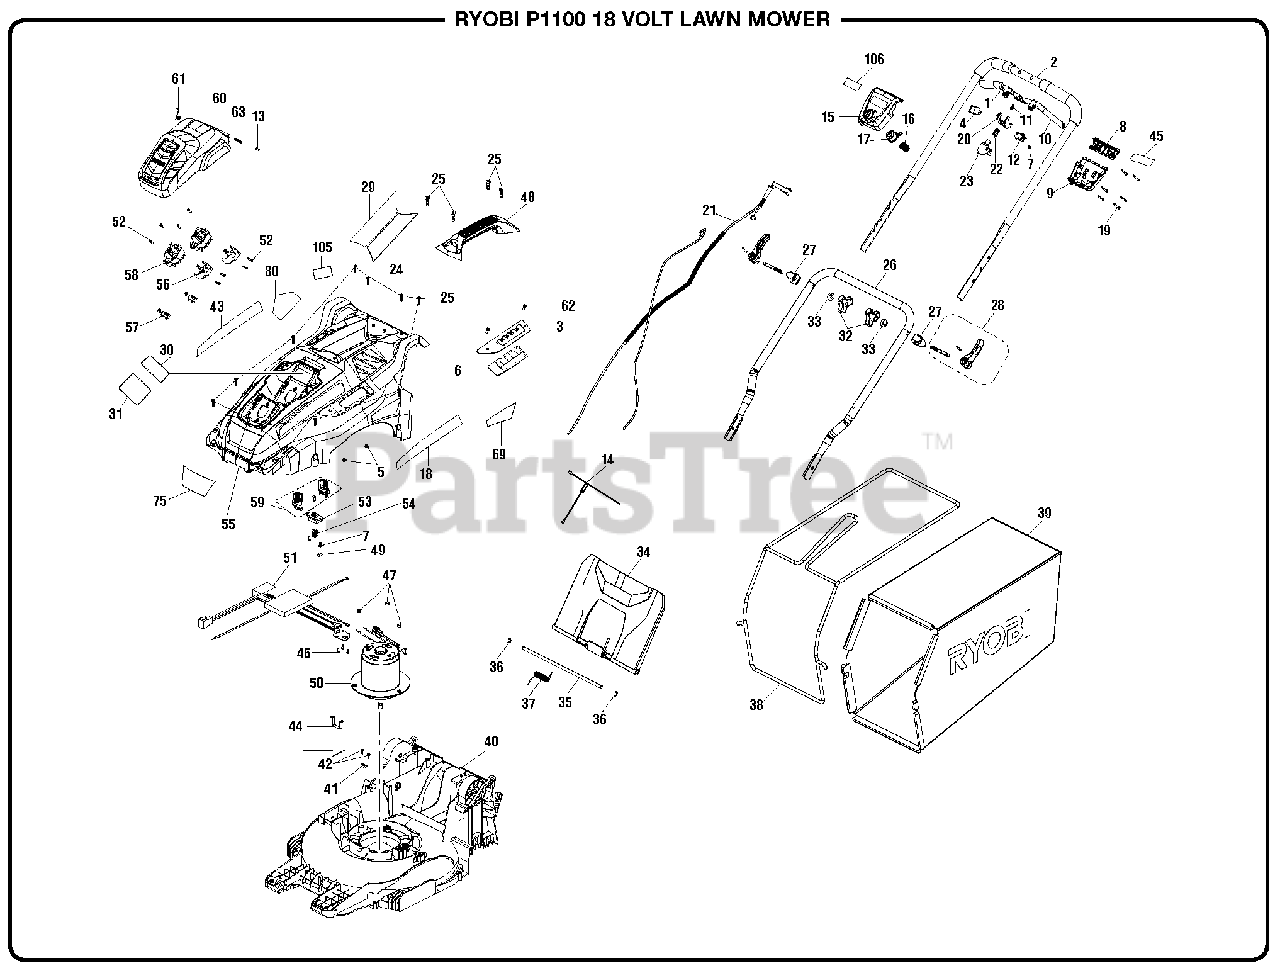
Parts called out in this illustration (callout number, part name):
1	Trigger Handle (Right Power Lever)
2	Upper Handle Assembly
3	Height Adjustment Plate
4	Cord Clamp
5	Lock Nut (M5)
6	Dust Gasket
7	Screw (M4 x 12 mm, T20 Torx Pan Hd.)
8	Lower Cover (Stain Handle)
9	Lower Cover (Trigger Housing)
10	Trigger Handle (Left Power Lever)
11	Compression Spring
12	Switch
13	Battery Door Axle
14	Lead Wire w/Terminal Block
15	Upper Cover (Control Assembly)
16	Button Return Spring
17	Start Button
18	Lithium Label (Left)
19	Screw (M4 x 30 mm, T15 Torx Pan Hd.)
20	Slider (Switch Box)
21	Starter Cable (Long)
22	Torsion Spring
23	Switch Holder
24	Warning Icon Label (Right)
25	Screw (M3.5 x 20 mm, T20 Torx Pan Hd.)
26	Lower Handle
27	Pressure Block
28	Handle Lock Assembly
29	Warning Icon Label (Left)
30	Start Key Label (Eng)
31	Start Key Label (FR/SP)
33	Block Washer
34	Rear Discharge Door
35	Rear Door Axle
36	Retaining Ring (E)
37	Torsion Spring (Rear Door)
38	Bag Frame
39	Bag
41	Cord Clip
42	Screw (M4.2 x 12 mm, T20 Torx Pan Hd.)
43	Lithium Label (Right)
44	Mounting Bracket
45	Starting Instructions Label
46	Screw (M3 x 8 mm,Phillip Pan Hd.)
47	Lock Nut (M6)
49	Rubber Cushion
51	Soft Start Circuit Board
52	Screw (M4 x 16 mm, T20 Torx Socket Pan Hd.)
53	Key Holder
54	Key Receptacle
55	Deck Cover
56	Press Cover (Battery Connect)
57	Plate (Battery Connect)
58	Base (Battery Connect)
59	Start Key
60	Battery Cover
61	Torsion Spring (Battery Door)
62	Screw (M5 x 0.8 mm, Pan Hd.)
63	Pressure Spring
75	Ryobi Logo Label (Front)
80	Cut Finger Label
105	Data Label
106	Ryobi Logo Label (Handle)
